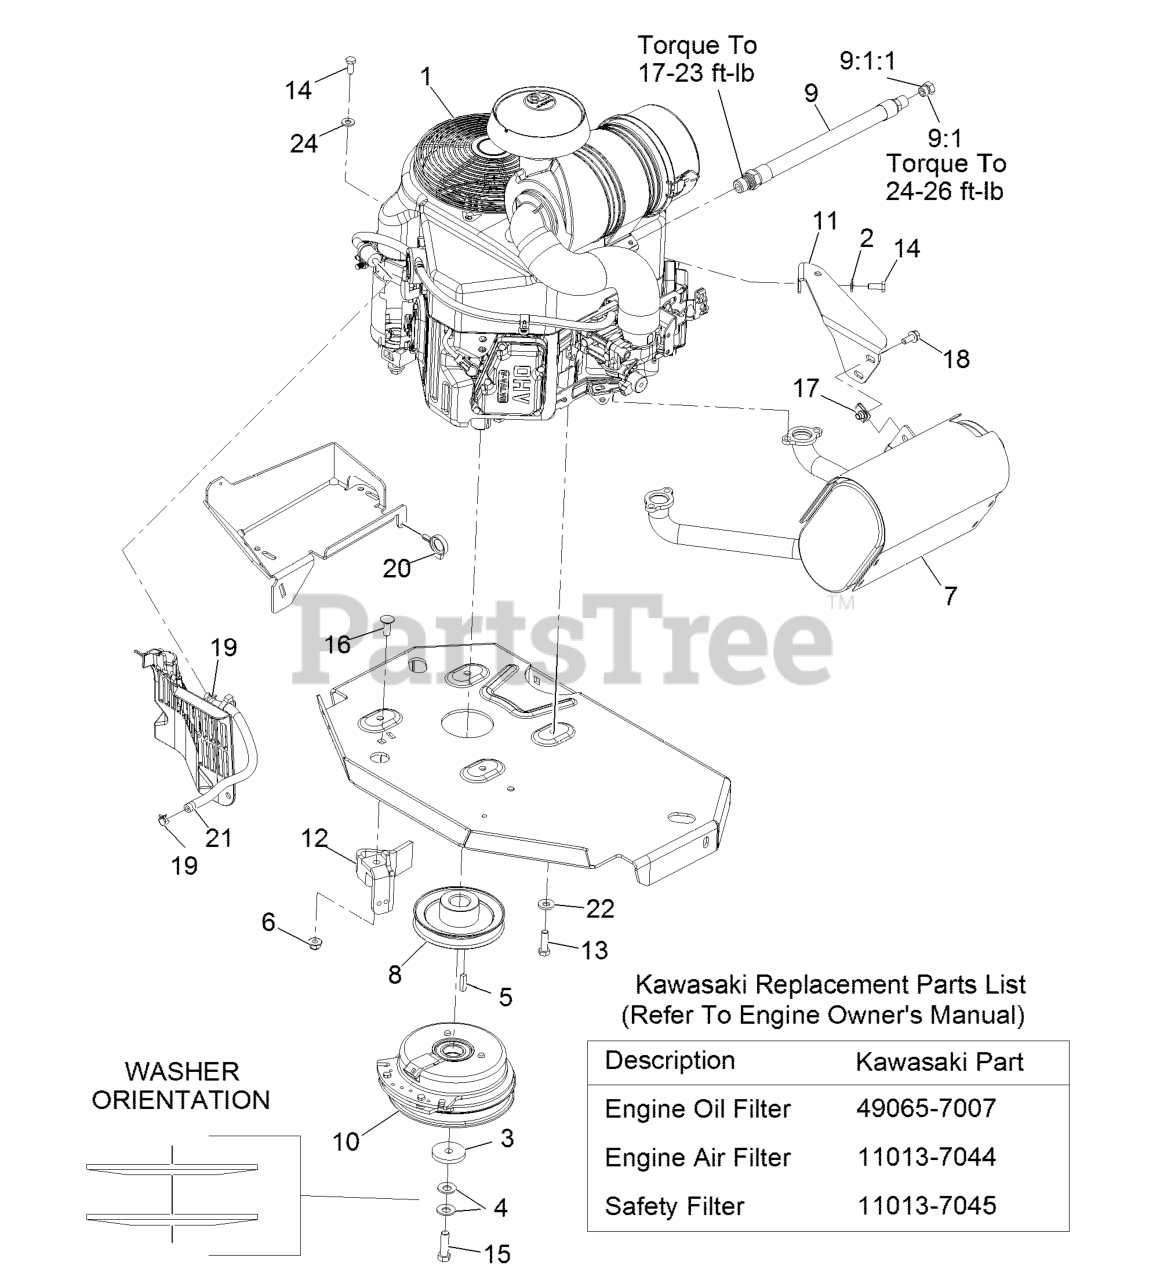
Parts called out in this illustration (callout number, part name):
2	WASHER-SPRING
3	WASHER-CLUTCH
4	WASHER-SPRING
6	NUT-HF, NI
7	MUFFLER
8	SHEAVE
9	ENGINE OIL DRAIN HOSE ASM
9:1	PLUG-HH
9:1:1	O-RING
10	CLUTCH KIT
11	BRACKET-MUFFLER
12	CLUTCH-ANCHOR
13	SCREW-HH
14	SCREW-HH
15	SCREW-HH 7/16-20 X 1 1/2 W/LOCTITE
16	SCREW-CARR
18	SCREW-HHF
19	CLAMP-HOSE
20	CLAMP-HOSE
21	HOSE-FUEL
22	WASHER-BELLEVILLE
24	WASHER-PLAIN
